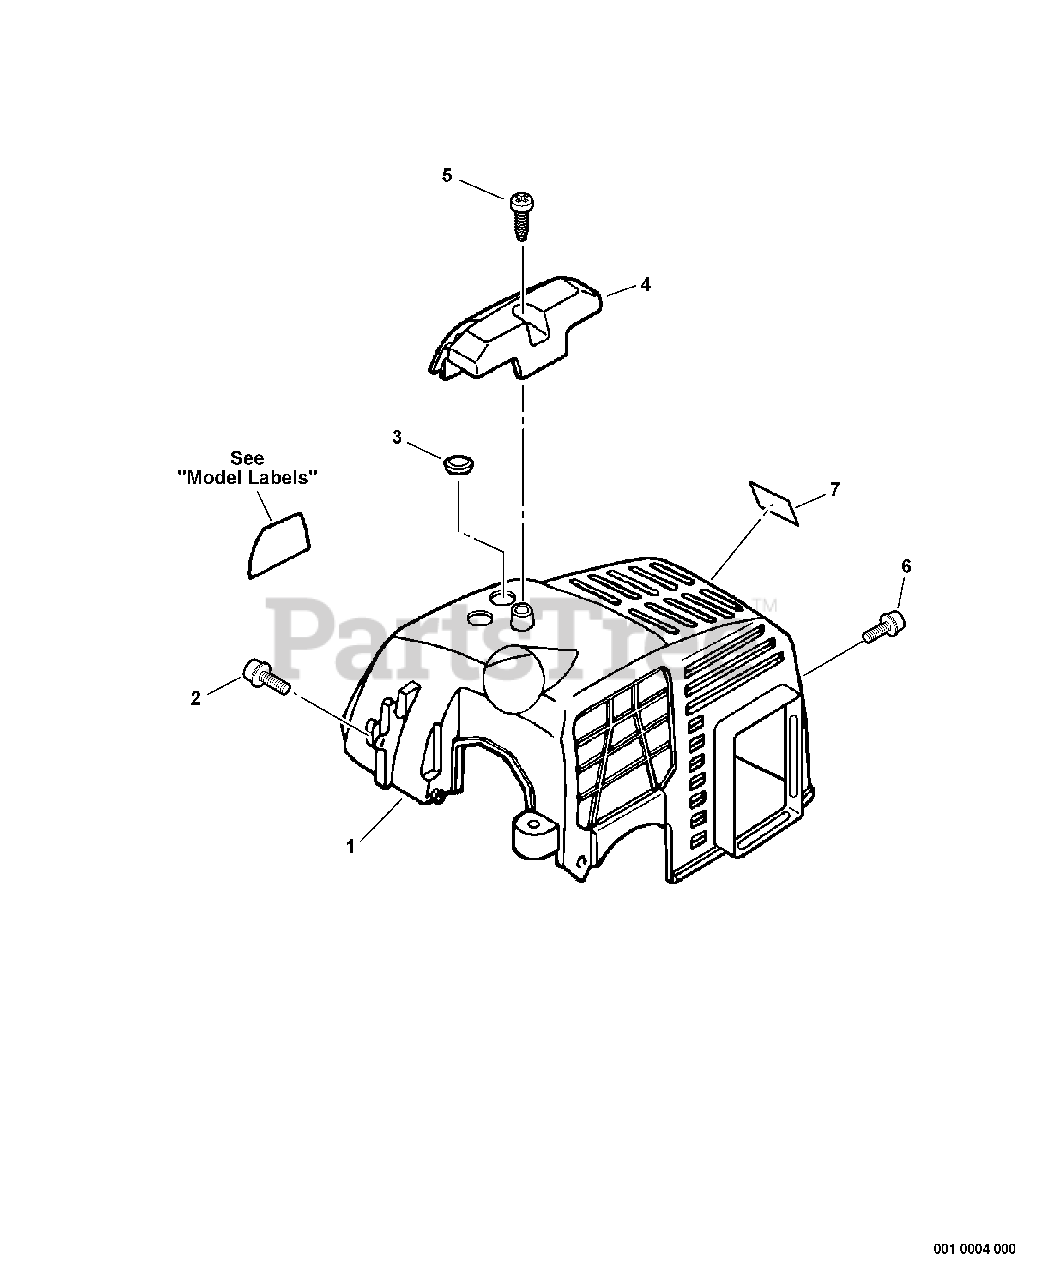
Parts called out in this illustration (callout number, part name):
1	COVER, ENGINE
2	SCREW 4×12
4	GUARD, TOP
5	SCREW 5×16
6	BOLT 4×8
7	LABEL, CAUTION - HOT
